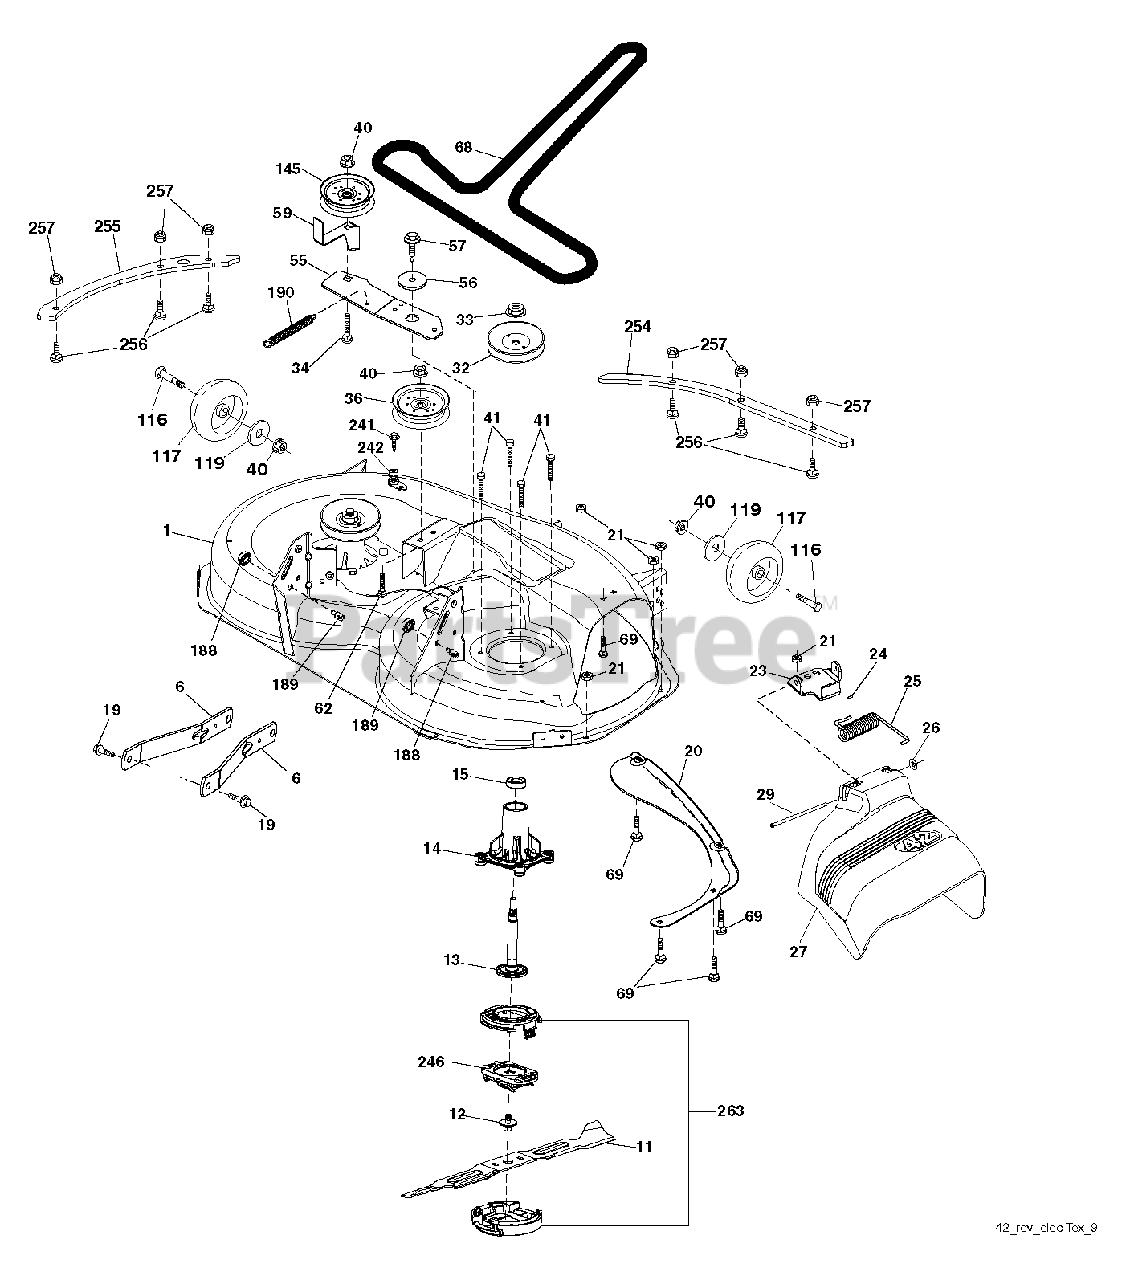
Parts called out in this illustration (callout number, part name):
1	DECK SVC 42"B 103 419175X498
6	ARM.SUSPENSION.MOWER.R
11	BLADE.REVOLUTION.42"3IN1.PT43
12	SCREW.SEMS.7/16-20X1.HEX.HEAD
13	SHAFT ASM.REV.TALL.N/GREASEBL
14	HOUSING.MANDREL.REV.TALL.N/GRS
19	BOLT.SHOULDER
20	BAFFLE.VORTEX
21	LOCKNUT
23	BRKT.DEFLECTOR.38"2005+
24	CAP-SLEEVE LT
25	SPRING.TORSION.DEFLECT
26	NUT PUSH M
27	SHIELD.DEFLECTOR.MOWER.42"BLAC
29	ROD.HINGE
32	PULLEY/MANDREL
33	NUT.FLANGE.LOCK.TOP
34	BOLT.3/8-16X1.50
36	PULLEY.IDLER.2006
40	NUT LOCK FLG 3/8-16 UNC
41	BOLT.HEX.WASHR.HED.313-18X1.19
55	IDLER.ARM.42"
56	SPACER.RETAINER
57	SCREW 3/8-16X1
59	GUARD, BELT
68	BELT V SECONDARY
69	BOLT
116	BOLT M
117	WHEEL.GAGE.HALF.SPOKED
119	WASHER
145	PULLEY.IDLER.48"PRIMARY
188	STUD.FASTNER.W/ANTI-ROTATE
189	NUT LOCK HEX FLANGE 5/16-18
190	SPRING.MOWER.DRIVE.ELECTRIC
241	SCREW.TT.#10-32X.5.3/8.FLANGE
242	PORT.WASHOUT
246	HOLDER.BLADE.REVOLUTION
254	PLATES.RENFRC.42DECK.PT431FRNT
255	PLATES.RENFRCE.42DECK.X431SIDE
256	RHSNB, 1/4-20 X 1, GR5
257	NUT T
263	CAP.REVOLUTION ASM
